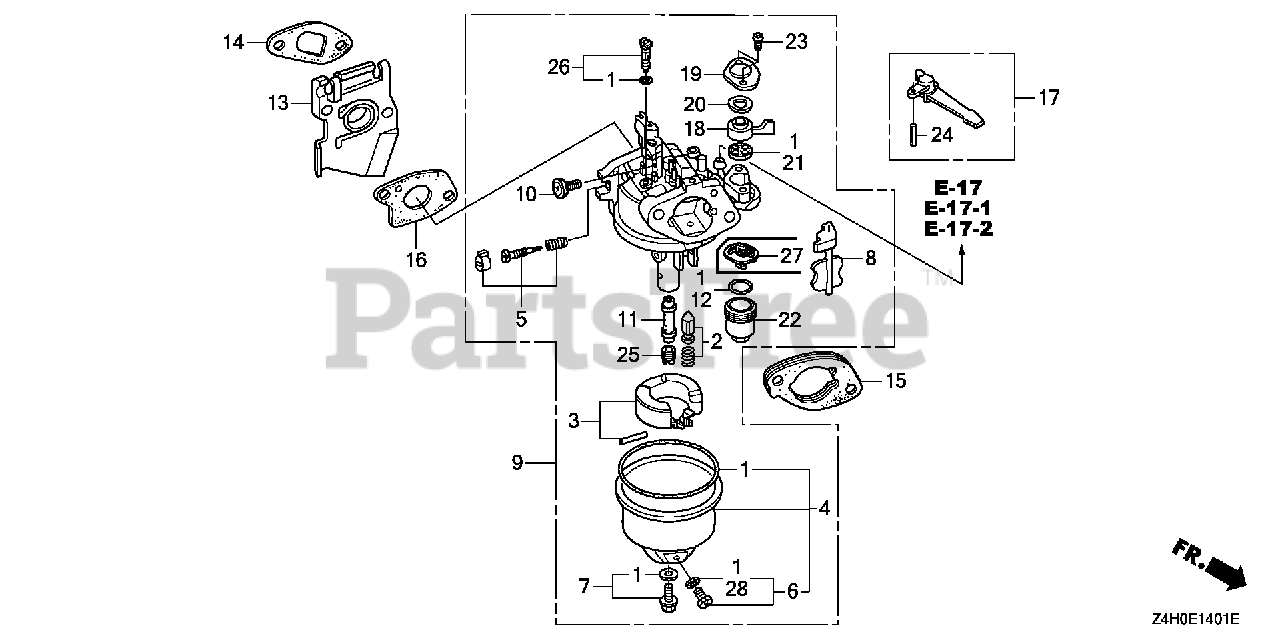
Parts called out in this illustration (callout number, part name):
1	GASKET SET
2	VALVE SET, FLOAT (SEAT NOT INCLUDED)
4	CHAMBER SET, FLOAT
5	SCREW SET, PILOT
6	SCREW SET, DRAIN
9	CARBURETOR ASSY. (BE60W A)
10	SCREW, THROTTLE STOP
11	NOZZLE, MAIN
12	GASKET, FUEL STRAINER CUP
13	INSULATOR, CARBURETOR
14	GASKET, INSULATOR
15	SPACER, CARBURETOR
16	GASKET, CARBURETOR
17	LEVER, CHOKE (STD)
18	LEVER, PETCOCK
19	PLATE, LEVER SETTING
20	SPRING, PETCOCK LEVER
21	GASKET, PETCOCK
22	CUP, FUEL STRAINER
23	SCREW, PAN (3X6)
24	PIN, SPRING (2X12)
25	JET, MAIN (#58)
25	JET, MAIN (#60)
25	JET, MAIN (#62)
26	JET SET, PILOT (#35)
27	FILTER, CUP
